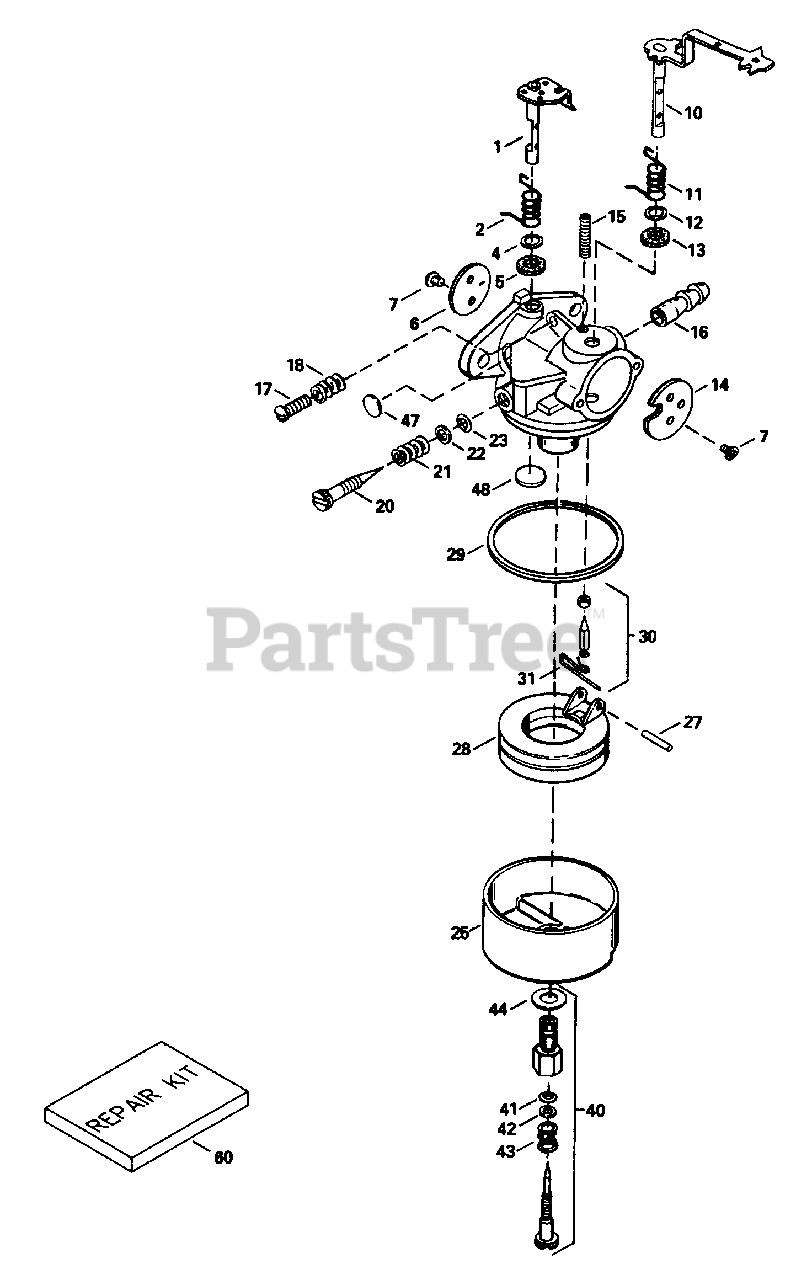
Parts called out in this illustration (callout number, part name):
1	Throttle Shaft & Lever Assy
2	Throttle Return Spring
4	Dust Seal Washer
5	Dust Seal
6	Throttle Shutter
7	Shutter Screw
10	Choke Shaft & Lever Assy
11	Choke Return Spring
12	Dust Seal Washer
13	Dust Seal
14	Choke Shutter
15	Choke Positioning Spring
16	Fuel Fitting
17	Throttle Crack Screw/Idle Speed Screw
18	Tension Spring
20	Idle Mixture Screw
21	Tension Spring
22	Idle Mixture Screw Washer
23	Idle Mixture Screw "O" Ring
25	Float Bowl
27	Float Shaft
28	Float
29	Float Bowl "O" Ring
30	Inlet Needle, Seat & Clip
31	Spring Clip
40	Main Adj. Screw Assy
41	High Speed Mixture Screw "O" Ring
42	High Speed Mixture Screw Washer
43	High Speed Mixture Screw Tension Spring
44	Bowl Nut Washer
47	Welch Plug, Idle Mixture Well
48	Welch Plug, Atmospheric Vent
60	Repair Kit
